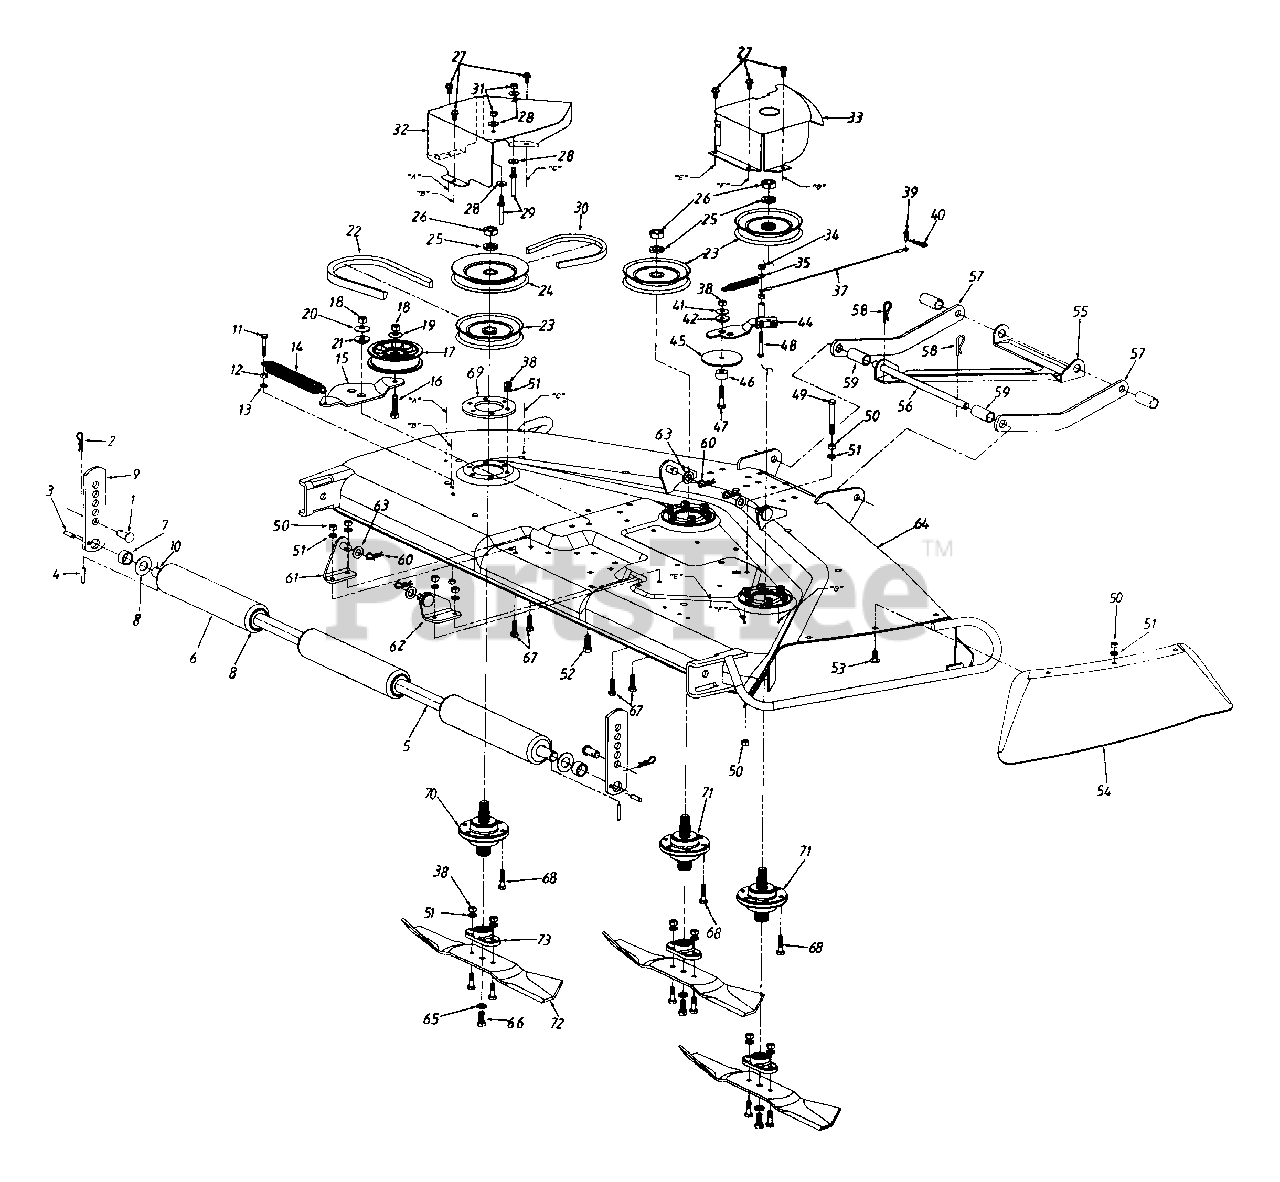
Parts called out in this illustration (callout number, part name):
1	Clevis Pin
2	Hairpin Clip
3	Spring Pin 1/4" x 1" Lg.
4	Spring Pin 3/16" x 1-1/4" Lg.
7	Spacer .75" I.D.
8	Fl-Wash. .76" I.D. x 1.5" O.D.
10	Roller Shaft
11	Hex Bolt 1/4-28 x 1.5" Lg. (Gr. 5)
12	Hex Nut 1/4-28 Thd.
13	L-Wash. 3/4" I.D.
14	Ext. Spring 7.33" Lg.
17	Idler Pulley
18	Hex Nut 3/8-24 Thd.
19	Bell-Wash. 3/8" I.D.
20	Bell-Wash. .39" I.D. x 1.13" O.D.
21	Shld. Spacer .625" I.D.
22	"V" Belt
23	Deck Pulley
24	Upper Deck Pulley
25	L-Wash. 5/8" I.D.
26	Hex Jam Nut 5/8-18 Thd.
27	Hex Wash. Hd. Scr. 1/4-20 x .5" Lg.
28	Bell-Wash. 1/4" I.D.
29	Belt Guard Pin
30	"V"-Belt
31	Hex Nut 1/4-20 Thd.
35	Ext. Spring 3.97" Lg.
37	Brake Cable
38	Hex Nut 5/16-24 Thd.
39	Clevis Pin
40	Hairpin Clip
41	Bell-Wash. .325" I.D.
42	Shld. Spacer
44	Brake Ass'y.
45	Fl-Wash. 5/16" I.D. x .3" O.D.
46	Spacer .44" Lg.
47	Hex Bolt 5/16-24 x 1.5" Lg. (Gr. 5)
48	Hex Bolt 1/4-28 x 1.75" Lg. (Gr. 5)
49	Hex Bolt 5/16-18 x 2.5" Lg.
50	Hex Nut 5/16-18 Thd.
51	L-Wash. 5/16" I.D.
52	Hex Bolt 3/8-24 x 1" Lg.
53	Carr. Bolt 5/16-18 x .75" Lg.
59	Spacer 1.75" Lg.
60	Hairpin Clip
61	Deck Hanger Brkt. - L.H.
62	Deck Hanger Brkt. - R.H.
63	Fl-Wash. 1/2" I.D. x .93" O.D.
66	Hex Bolt 3/8-24 x .88" Lg. (Gr. 5)
67	Hex Bolt 5/16-18 x 1" Lg.
68	Hex Bolt 5/16-24 x 1-1/4" Lg. (Gr. 5)
69	Spindle Reinforcement Plate
70	Spindle Ass'y. (L.H.)
71	Spindle Ass'y. (R.H. & Center)
72	Blade
73	Blade Adapter
